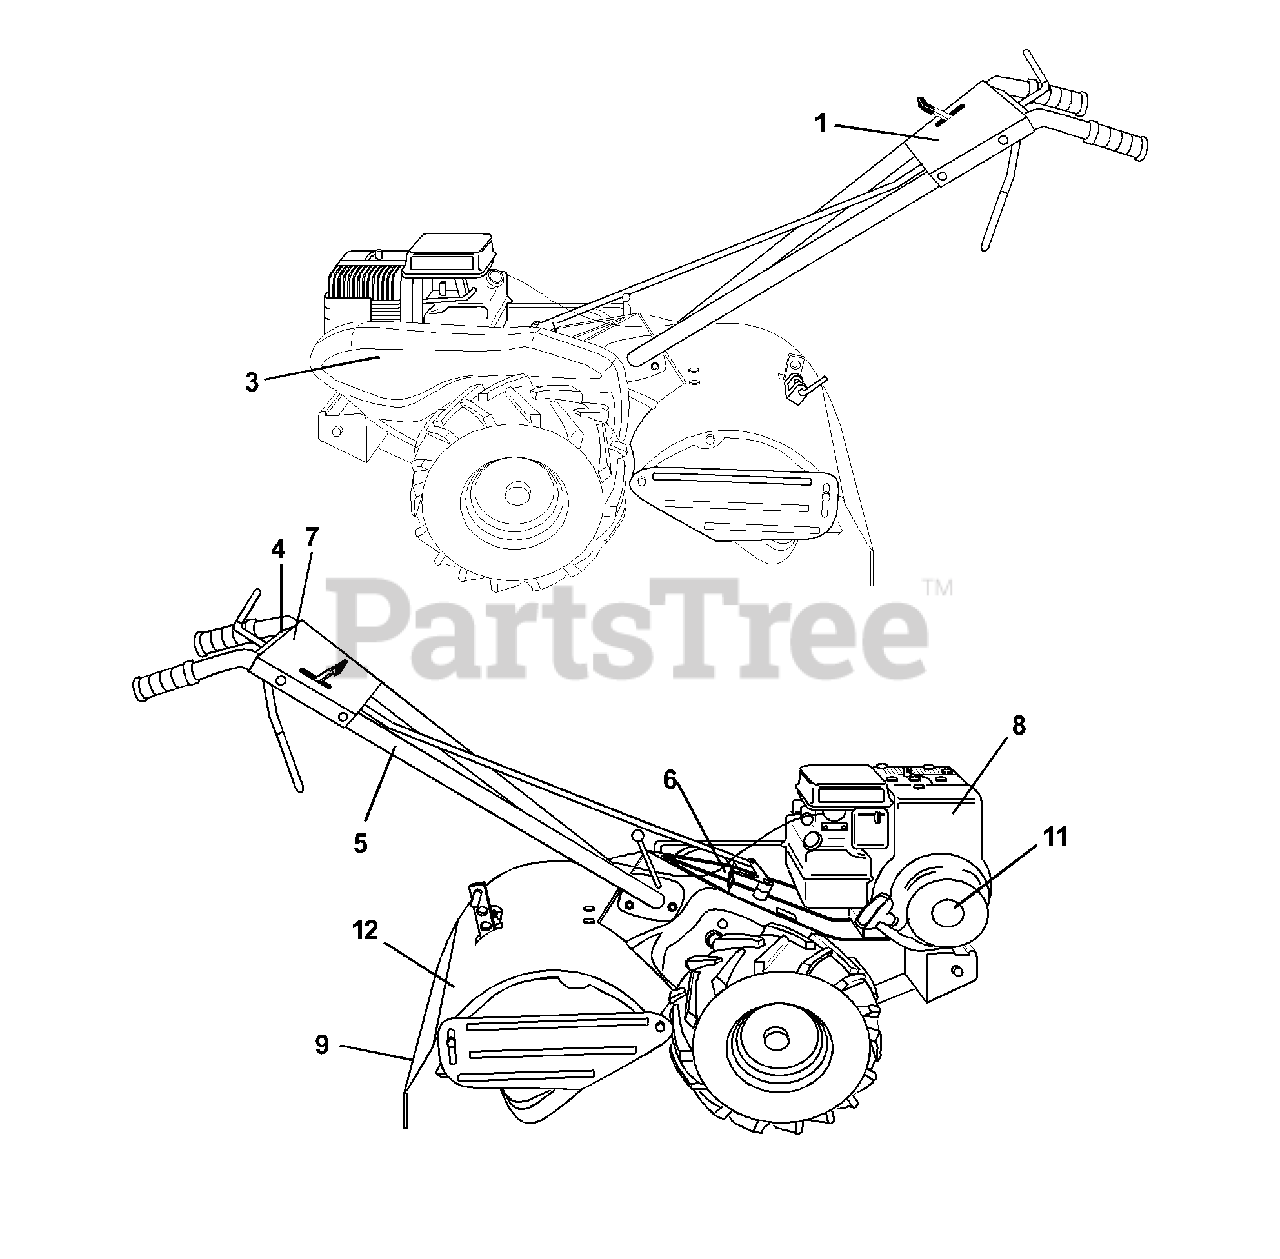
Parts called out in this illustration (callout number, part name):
1	Decal, Logo
3	Decal, Logo
4	Decal, Instruction, Tilling
5	Decal, Hand Placement
6	Decal, Shift Indicator
7	Decal, Pnl Cntrl Reverse
8	Decal, Briggs & Stratton
9	Decal, Warning, Rotating Tines
11	Decal, 5 HP
12	Decal, Warning Till
